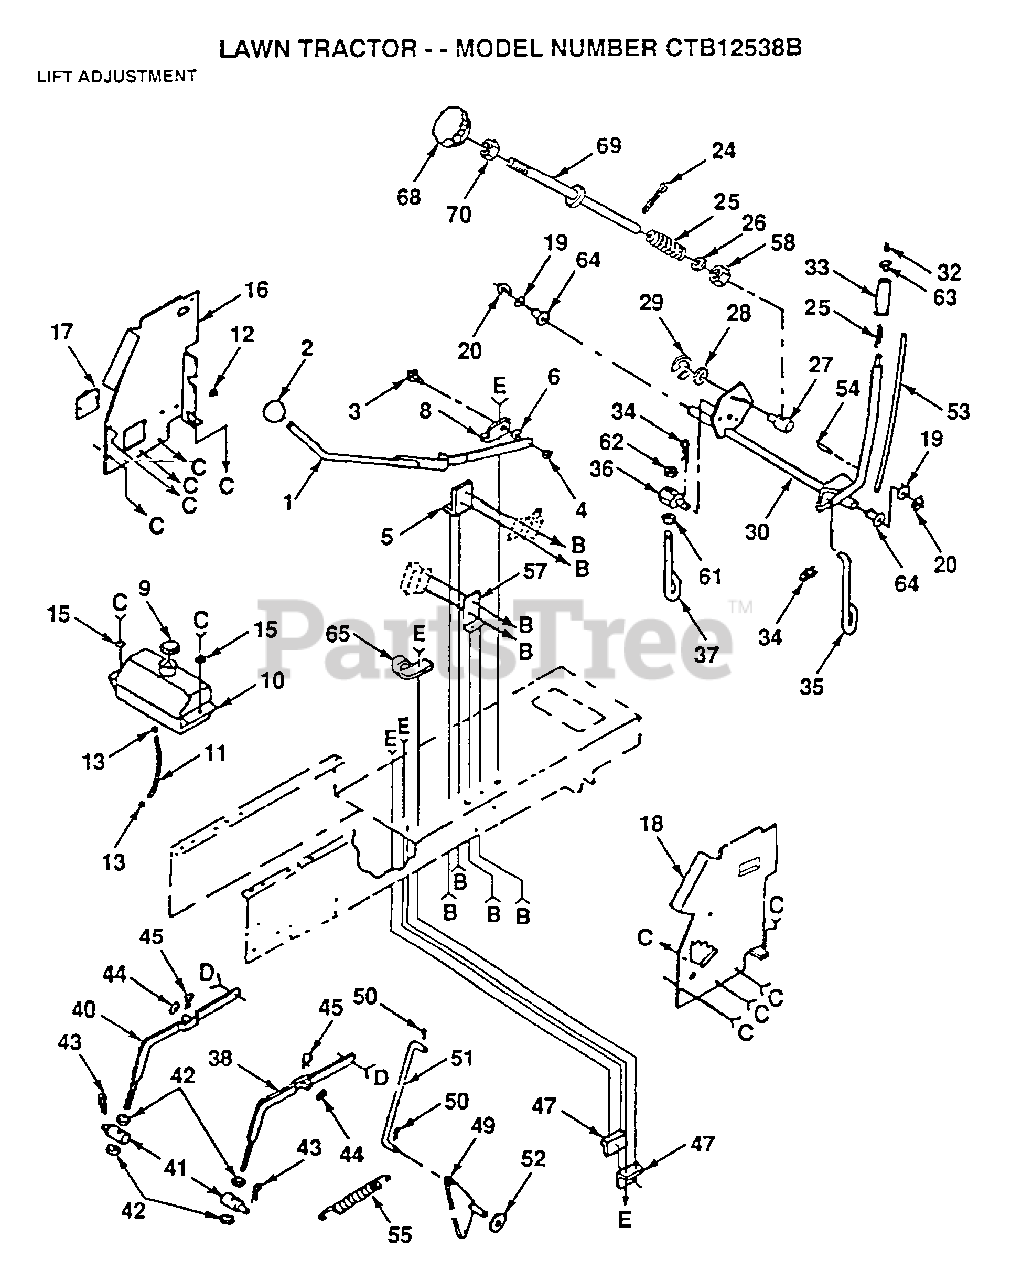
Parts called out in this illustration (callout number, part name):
3	"BOLT, SHOULDER LT"
5	"BRACKET,SWITCH LT"
8	"SUP,LVR,CLUTCH LT"
10	TANK.FUEL.LT.
11	FUEL LINE T
12	SNAP BUSHING T
13	HOSE CLAMP
15	WASHER GT
16	PANEL DASH LH
17	COVER ACCESS
19	WASHER
25	SPRING T
26	WASHER
27	TRUNION LT
28	WASHER
29	KLIP RING
33	GRIP
35	LIFT LINK LT
37	PIVOT PIN T
38	RH SUSP ARM ASM
40	LH SUSP ARM ASM
42	NUT
43	SPRING H
45	SPRING.RETAINER
47	"BRKT,BELLCRAN T"
49	"T, BELLCRANK"
50	COTTER PIN
52	WASHER
54	PIN-GROOVE LT
57	BRACKET LT
58	NUT T
61	NUT
64	NYLON BEARING
65	INSUL CLIP T
70	NUT
